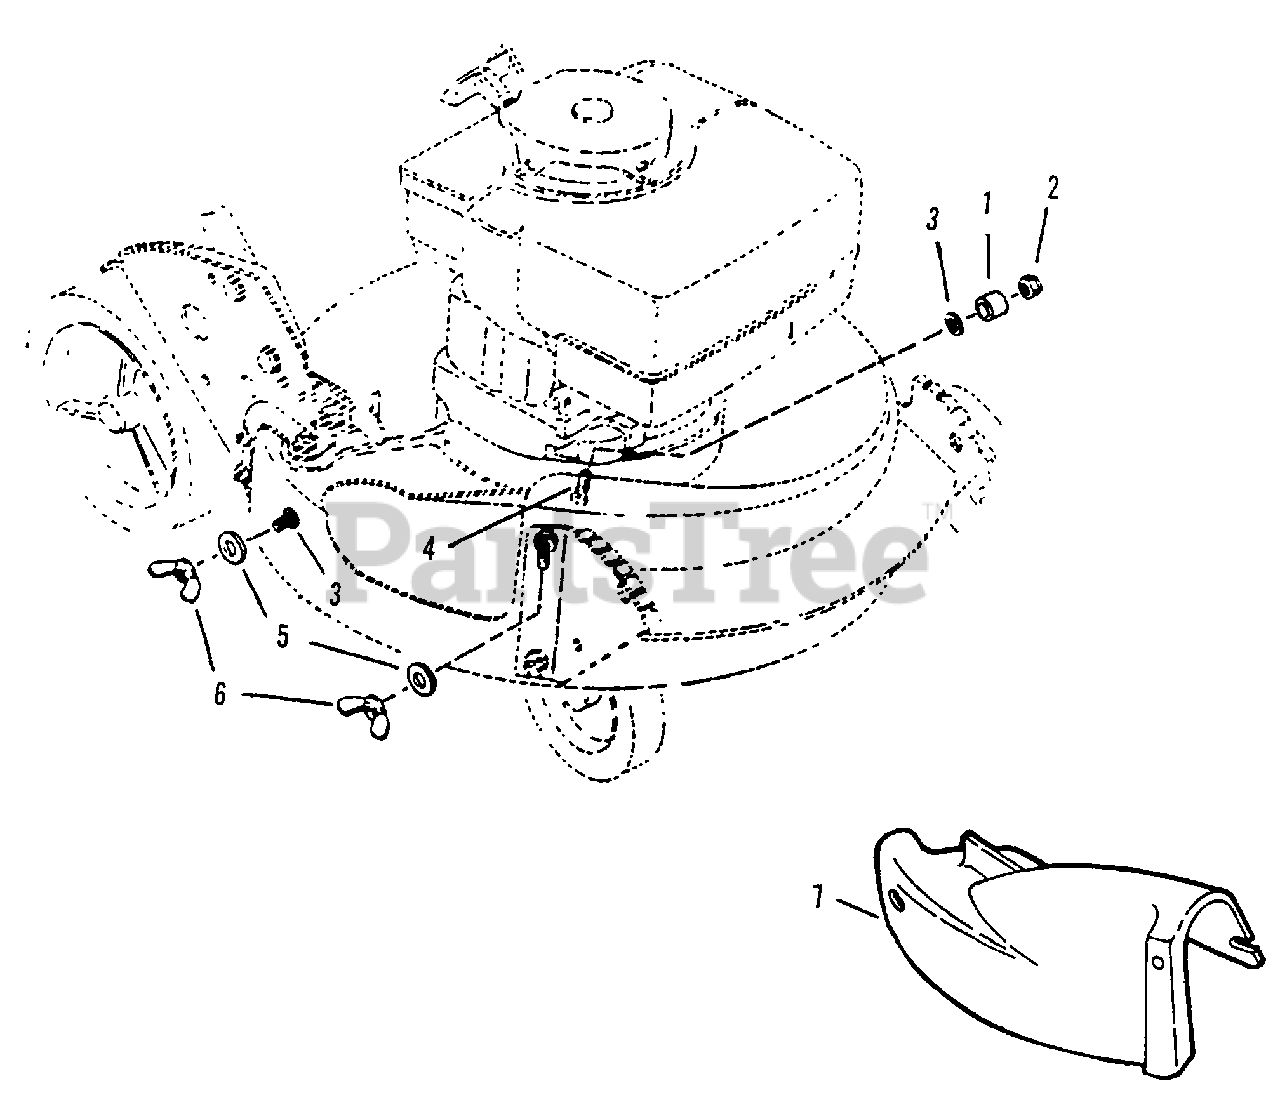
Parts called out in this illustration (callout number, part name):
1	SPACER
2	NUT, 5/16-18 Hex Flange Center Lock
3	RETAINER, 5/16 Bolt
4	BOLT, 5/16-18 x 3/4" Short Neck Carriage, Grade 5
5	WASHER, 5/16 Flat
6	WING-NUT, 5/16-18 Nyloc
7	COVER, 21" Deck
